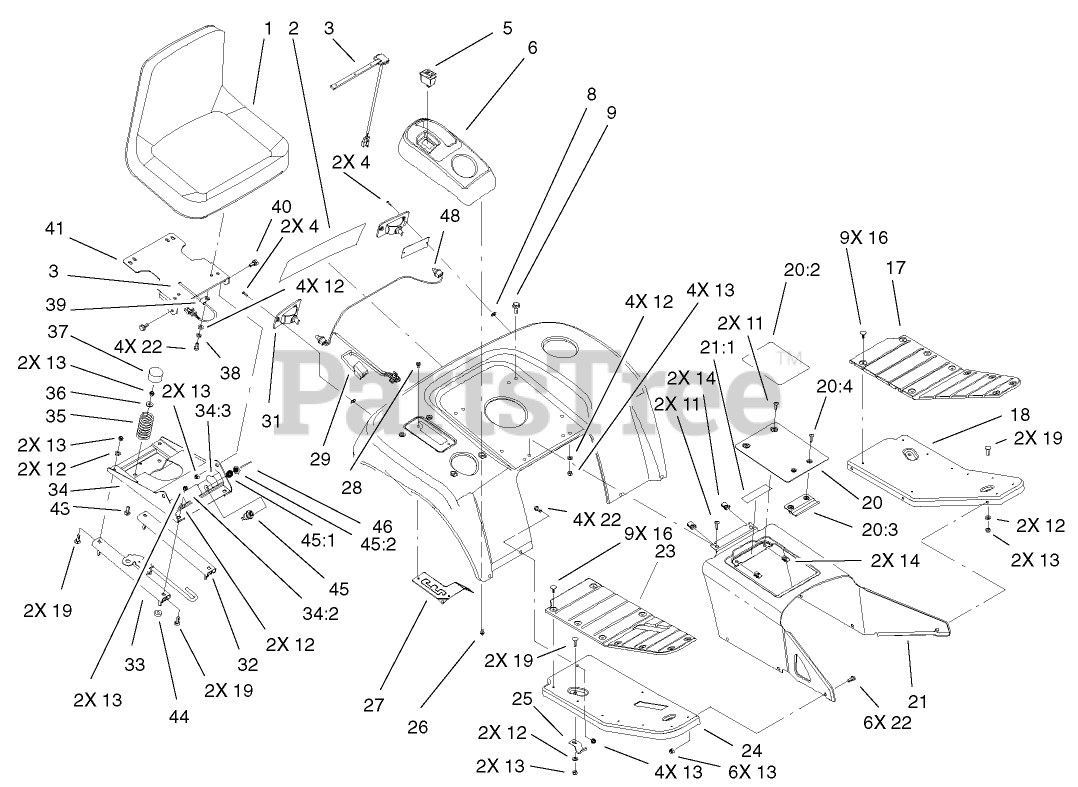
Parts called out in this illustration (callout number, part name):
3	SWITCH-SEAT
4	SCREW-PPH
5	SWITCH-CRUISE
6	POD-CONTROL
6	POD - CONTROL INT'L
8	NUT-SPEED
9	SCREW-HHF
11	SCREW-HH
12	WASHER-PLAIN
13	NUT-LOCK, NI
16	FASTENER-PANEL
17	PAD-FOOTREST, LH
18	FOOTREST-LH
19	SCREW-CARR
20	TUNNEL COVER ASM
20:2	DECAL - DANGER
20:2	DECAL-DANGER
20:3	RETAINER-COVER
20:4	SCREW-PPH
21	TUNNEL ASM
21:1	DECAL - WARNING
21:1	DECAL-DANGER
22	SCREW-HH
24	FOOTREST-RH
25	BRACKET-FOOTREST
26	SCREW-HWH
27	GATE-HI / LO SHIFT
28	SCREW-HWH
29	HARNESS-REAR
31	LAMP-TAILLIGHT
32	SLIDE-SLAVE, SEAT
33	SLIDE-LATCH, SEAT
34	SEAT BASE ASM
34:2	DECAL-DANGER
34:3	DECAL-SWITCH
34:3	DECAL-SWITCH, NMIR
35	SPRING-COMPRESSION
36	BUSHING
37	CAP-SPRING, SEAT
38	WASHER-LOCK
39	CLAMP-R
40	BOLT-SHOULDER,HFH
43	SCREW-CARR
44	WASHER-FLAT
45	STARTER SWITCH ASM
45:1	WASHER-LOCK
45:2	NUT-HH
46	KEY-IGNITION
48	LIGHT BULB
